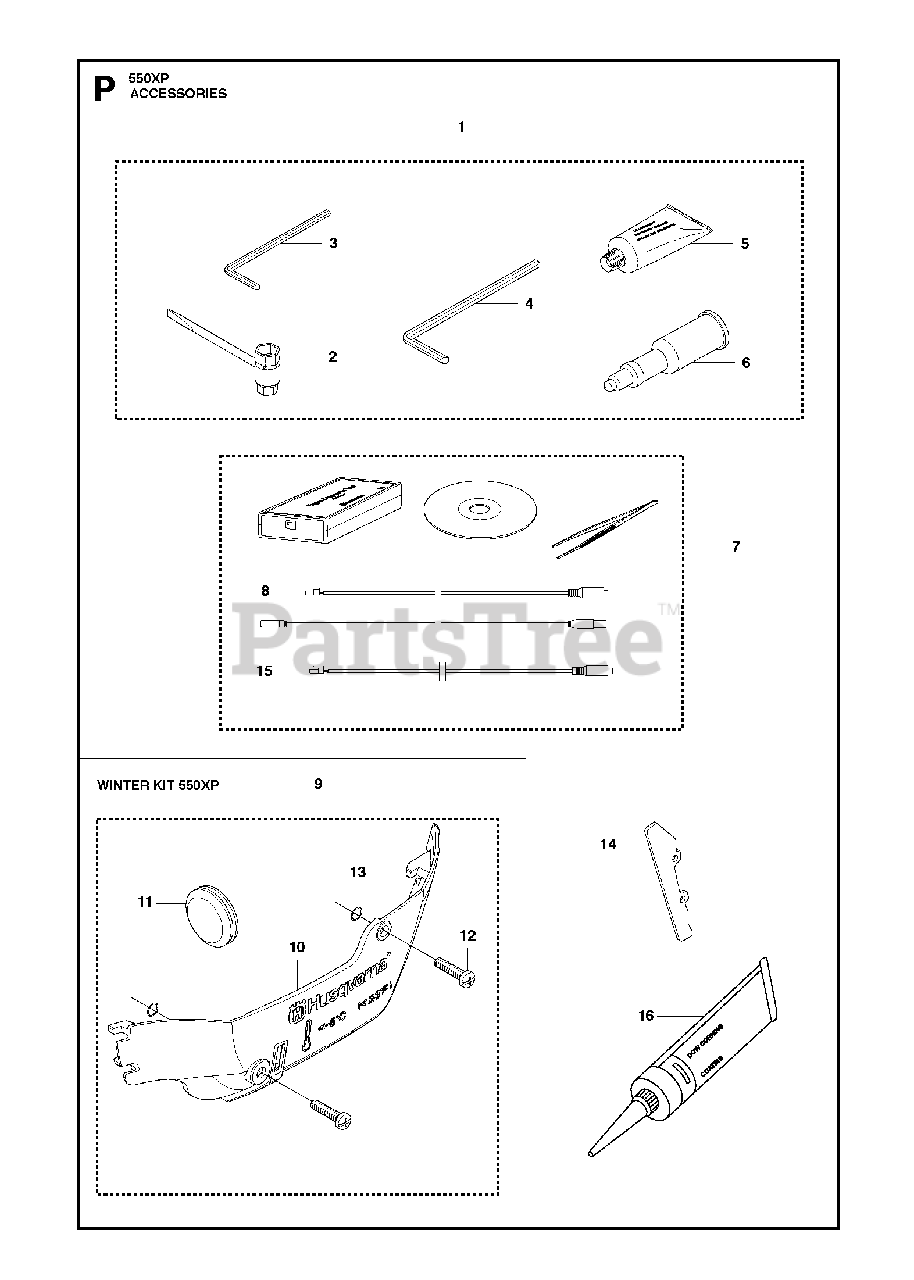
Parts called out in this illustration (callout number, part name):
2	COMBINATION WRENCH
3	L-SPANNER
4	L-SPANNER
5	GREASE
6	Grease Gun
7	SERVICE TOOLS
8	CABLE ASSY
9	WINTER KIT
10	WINTER COVER
11	WINTER PLUG
12	SCREW
13	O-RING
14	BUMPER, BAG
15	CABLE ASSY
